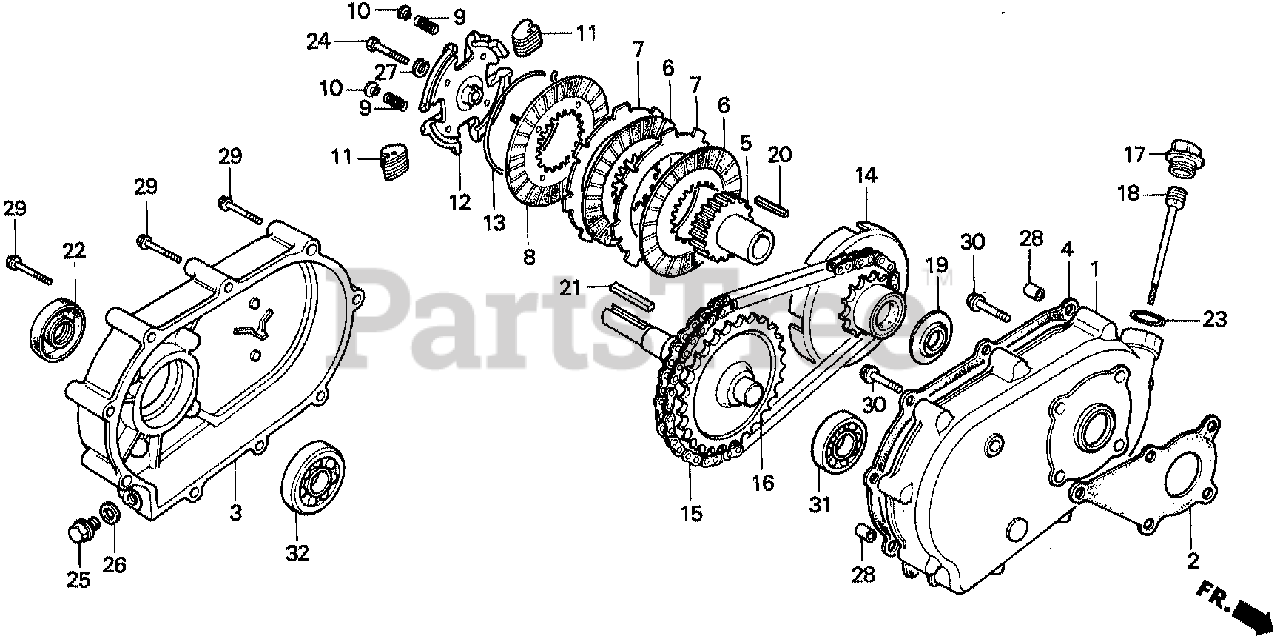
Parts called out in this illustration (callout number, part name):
1	CASE, REDUCTION
2	GASKET, REDUCTION CASE
3	COVER, REDUCTION
4	GASKET, REDUCTION COVER
5	CENTER, CLUTCH
6	DISK, CLUTCH FRICTION
7	PLATE, CLUTCH
8	PLATE, CLUTCH PRESSURE
9	SPRING, CLUTCH FREE
10	HOLDER, CLUTCH SPRING
11	WEIGHT, CLUTCH
12	HOLDER, CLUTCH WEIGHT
13	CENTER, CLUTCH WEIGHT
14	SPROCKET, DRIVE
15	CHAIN, DRIVE (RK428SH-36LE)
16	SHAFT, P.T.O. (28T)
17	CAP, REDUCTION OIL
18	DIPSTICK, OIL
19	WASHER, THRUST (20MM)
20	KEY (5MM)
21	KEY (7X7X33)
22	OIL SEAL (PJ30507)
23	O-RING (26X2.7)
24	BOLT, HEX. (8X36)
24	BOLT, HEX. (8X35)
25	BOLT, DRAIN PLUG (12MM)
26	WASHER, DRAIN PLUG (12MM)
27	WASHER, SPRING (8MM)
28	PIN A, DOWEL (8X10)
29	BOLT, FLANGE (6X55)
30	BOLT, FLANGE (8X22)
31	BEARING, RADIAL BALL (6205)
32	BEARING, RADIAL BALL (6206)
